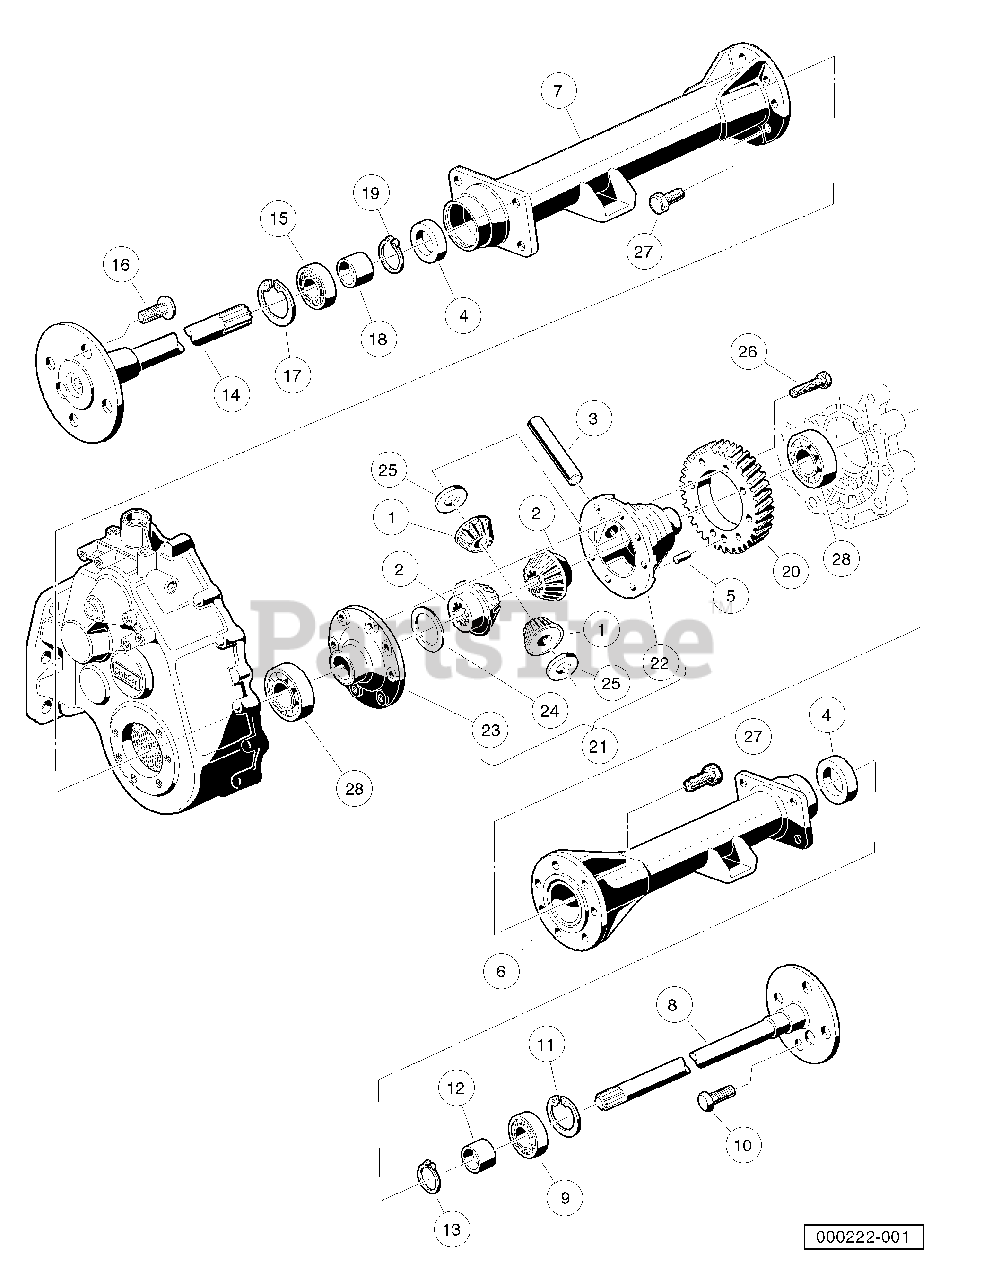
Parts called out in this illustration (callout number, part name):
1	Differential Idler Gear
2	Gear, Differential
3	Pin, Differential
4	Axle Shaft Oil Seal
5	Dowel Pin
8	Axle Assembly, Passenger Side
9	Outer Axle, Tube Bearing
11	Circlip Type C
13	Retaining Ring
14	Axle Assembly, Driver-Side
15	Outer Axle, Tube Bearing
17	Circlip Type C
19	Retaining Ring
20	Gear, Helical
21	Kit, Differential Gear Case
22	Differential Gear Case, Left-Hand
23	Differential Gear Case, Right-Hand
24	Plate, Thrust
25	Plate, Thrust
26	Screw, M8-1.25 X 35mm Hex Head
27	Bolt, M10 X 1.5 X 30mm
28	Inner Axle Tube Bearing
